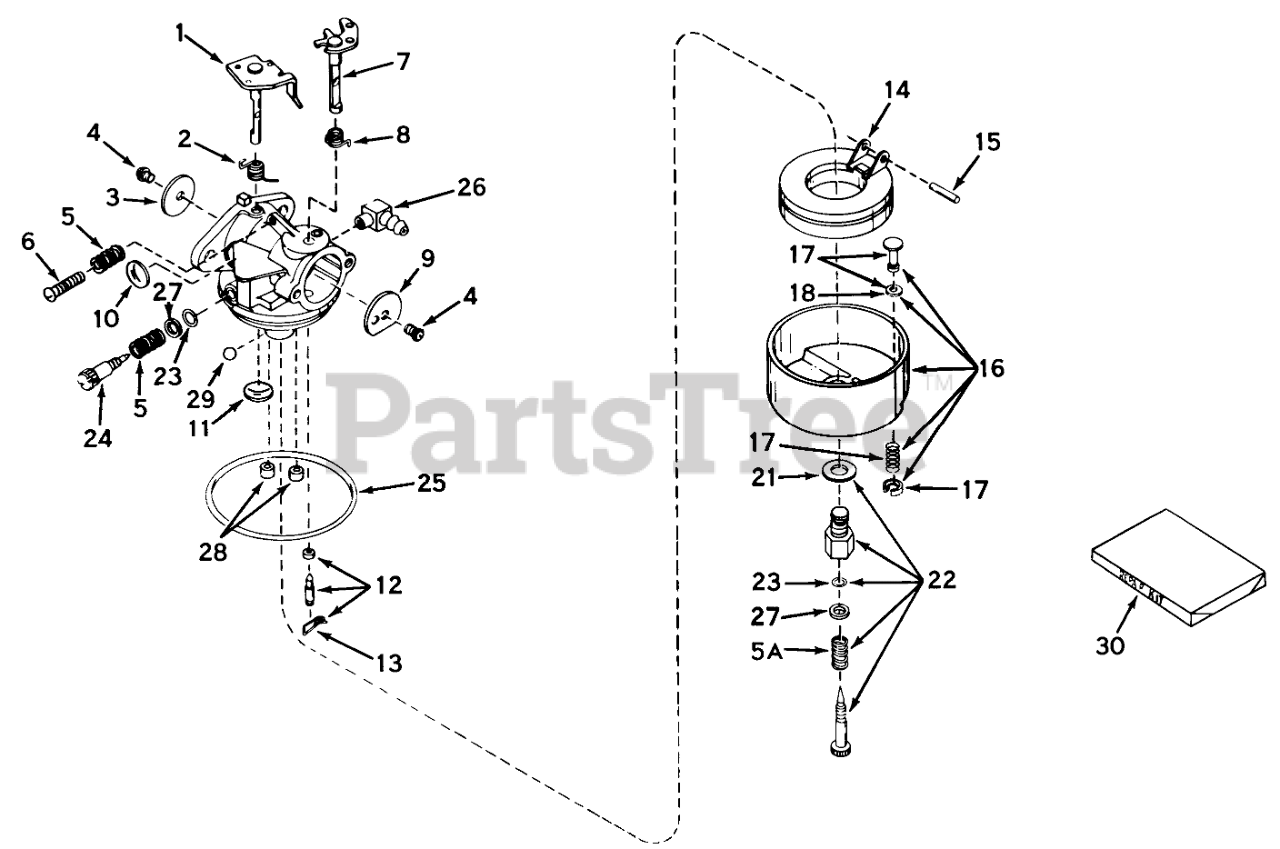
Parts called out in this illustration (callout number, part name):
1	Shaft & Lever Assy.
2	Spring Return
3	Shutter-Throttle
4	Screw-Shutter
5	Spring-Tension
6	Screw-Throttle Crack Screw / Idle Speed
7	Shaft& Lever Assy., Choke
8	Spring, Choke return
9	Shutter-Choke
10	Plug-Welch, Idle Mixture Well
11	Plug-Welch, Atmospheric Vent
12	Inlet Needle, Seat & Clip Assy. (Incl. No. 13)
13	Clip-Spring
14	Float,Carburetor
15	Shaft-Float
16	Bowl & Drain Assy., Float (Incl. Nos. 17, 19 & 20)
17	Plunger Assy., Drain (Incl. No. 18)
18	Gasket-Plunger, Drain
19	Spring, Drain Plunger
20	Retainer, Plunger Spring
21	Washer-Bowl Nut
22	Adjustment Screw Assy., Main (Incl. Nos. 5A, 21, 23 & 27)
23	"O"Ring
24	Screw, Idle Adj.
25	O Ring-Bowl, Float
26	Fitting Fuel Inlet
28	Plug, Cup
29	BalI, Steel
30	Repair Kit
